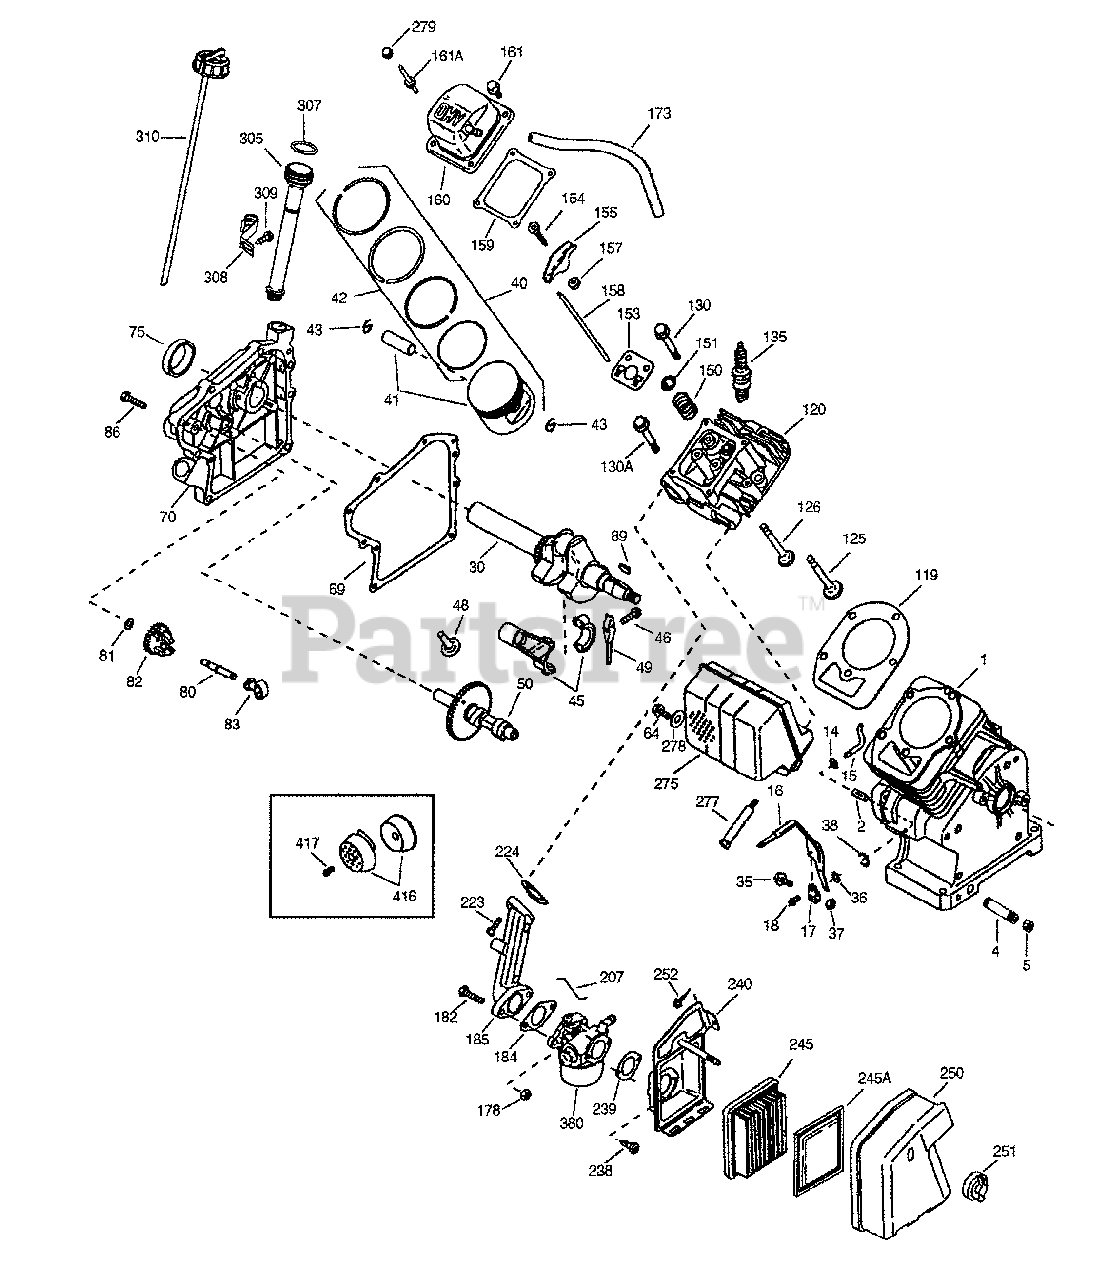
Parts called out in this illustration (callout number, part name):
1	Cylinder
2	Dowel Pin
4	Oil Drain Extension
5	Extension Cap
15	Governor Rod
16	Governor Lever
17	Governor Lever Clamp
18	Screw, 8-32 x 5/16"
30	Crankshaft
35	Screw, 10-32 x 3/4"
36	Lock Washer
37	Lock Nut, 10-32
38	Retaining Ring
40	Piston, Pin & Ring Set (Standard)
41	Piston & Pin Ass'y (Standard)
42	Ring Set (Standard)
43	Piston Pin Retaining Ring
45	Connecting Rod Ass'y
46	Connecting Rod Bolt
48	Valve Lifter
49	Oil Dipper
50	Camshaft
64	Screw, 1/4-20 x 1-1/8"
69	Cylinder Cover Gasket
70	Cylinder Cover
80	Governor Shaft
82	Governor Gear Ass'y
83	Governor Spool
86	Screw, 1/4-20 x 1-1/4"
89	Flywheel Key
119	Cylinder Head Gasket
120	Cylinder Head
125	Exhaust Valve (Standard)
126	Intake Valve (Standard)
130	Screw, 5/16-18 x 1-1/2"
130A	Screw, 5/16-18 x 2-41/64"
135	Resistor Spark Plug (N4C)
150	Valve Spring
151	Valve Spring Cap
153	Push Rod Guide
154	Rocker Arm Stud
155	Rocker Arm
157	Nut, 1/4-28
159	Rocker Arm Cover Gasket
160	Rocker Arm Cover
161	Screw, 1/4-20 x 31/64"
173	Breather Tube
178	Nut, 1/4-20
182	Screw, 1/4-20 x 1"
184	Carb. to Intake Pipe Gasket
185	Intake Pipe
207	Throttle Link
223	Screw, 1/4-20 x 1"
224	Intake Pipe Gasket
238	Screw, 10-32 x 1/2"
239	Air Cleaner Gasket
240	Air Cleaner Body
245	Air Cleaner Filter
245A	Air Cleaner Filter (Poly)
250	Air Cleaner Cover
252	Screw, 10-32 x 31/64"
277	Screw, 1/4-20 x 2-9/32"
279	Nut & Lock Washer
305	Oil Fill Tube
308	Fill Tube Clip
309	Screw, 10-32 x 5/16"
310	Dipstick
380	Carburetor Assembly
416	Spark Arrestor Kit
417	Screw, 8-32 x 3/8"
